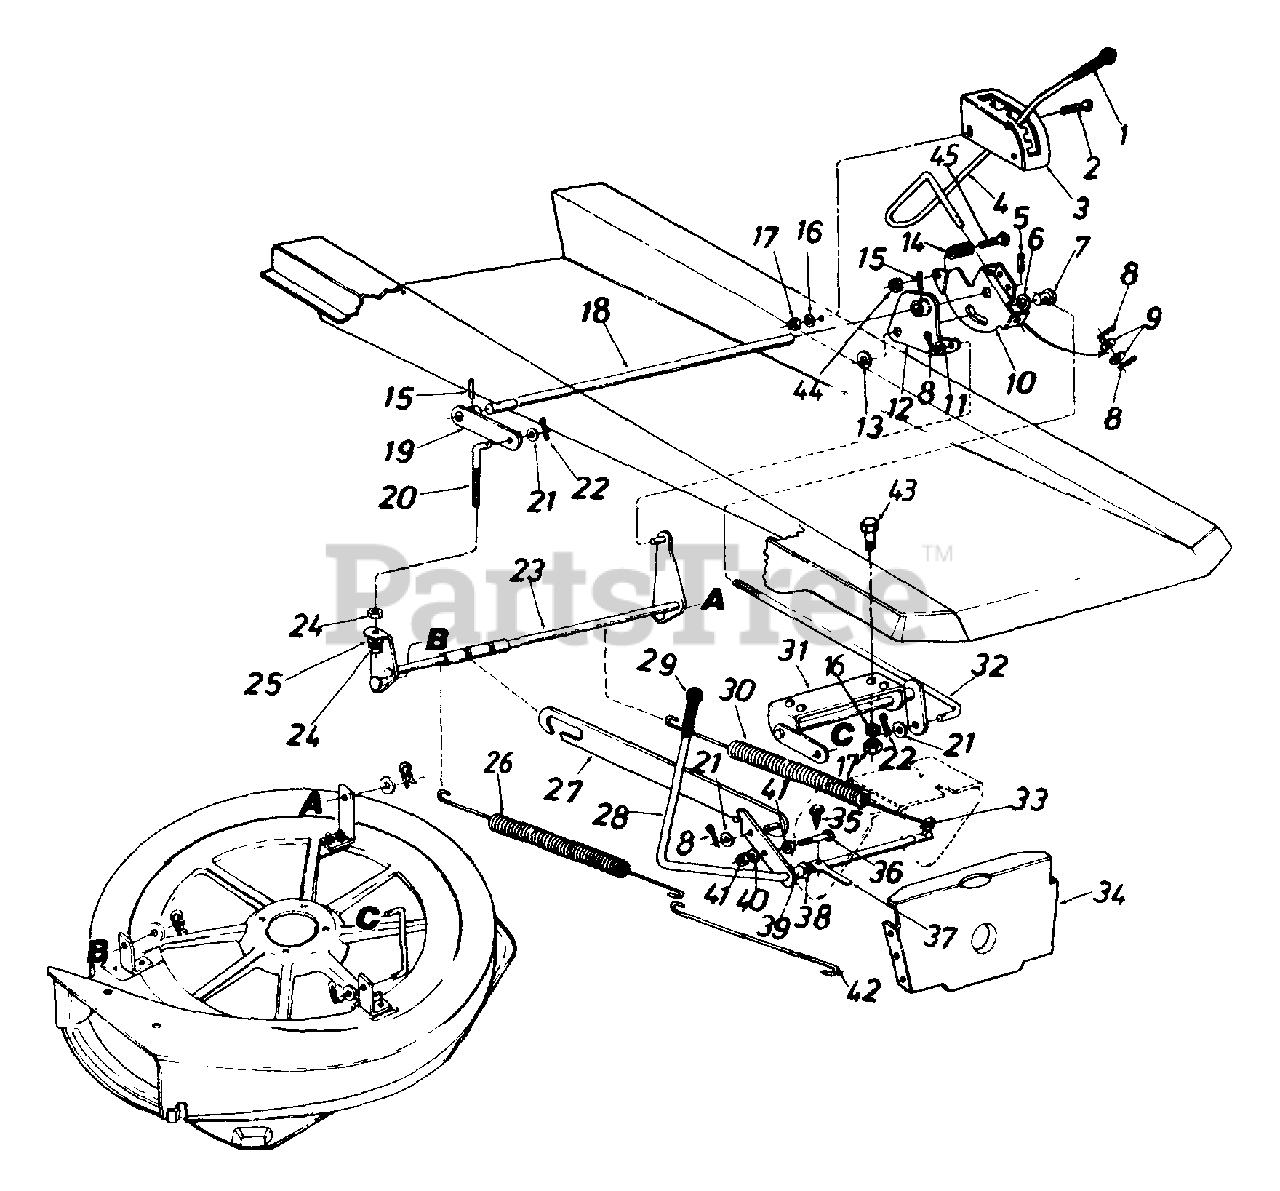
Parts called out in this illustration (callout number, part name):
2	Truss Mach. Scr. 5/16-18 x .75" Lg.
5	Spring Pin Spir. 3/16" Dia. x 1.50" Lg.
6	Fl-Wash. .385" I.D. x .87" O.D.
7	Adj. Ferrule Deck Lift Handle
8	Cotter Pin 1/8" Dia. x 1.0"
9	Fl-Wash. .531" I.D. x .930" O.D.
12	Deck Lift Brkt. Ass'y. - L.H.
13	Fl-Wash. .635" I.D. x 1.04" O.D.
14	Compression Spring .5" Dia. x .9" Lg.
15	Spring Pin Spir. 1/4" Dia. x 1.50" Lg.
16	L-Wash. 5/16" I.D."
17	Hex Nut 5/16-18 Thd.
18	Rear Hgt. Adj. Shaft
19	Deck Lift Brkt. Ass'y. - R.H.
20	Deck Adj. Scr. 3/8-16 Thd.
21	Fl-Wash. .385" I.D. x .87" O.D.
22	Intern. Cotter Pin 1/2" Dia.
23	Deck Link Ass'y. - Rear
24	Hex Nut 3/8-16 Thd.
25	L-Wash 3/8" I.D
26	Extension Spring 13.25" Lg
30	Extension Spring 13.25" Lg.
31	Deck Lift Ass'y. - Front
32	Deck Lift Connecting Rod
33	Clevis Pin Special .250" Dia.
36	Hex Bolt 5/16-18 x 1.50" Lg (Grade 5)
37	Switch Actuator
38	Fl-Wash .531" I.D. x .930" O.D.
39	Spacer .511" I.D. x .70" O D x .38" Lg
40	L-Wash. 5/16" I D.
41	Hex Nut 5/16-18 Thd.
42	Spring Hook
43	Hex Bolt 5/16-18 x 75" Lg
44	Hex Cent. L-Nut 1/4-20 Thd.
45	Hex Bolt 1/4-20 x 1 25" Lg
